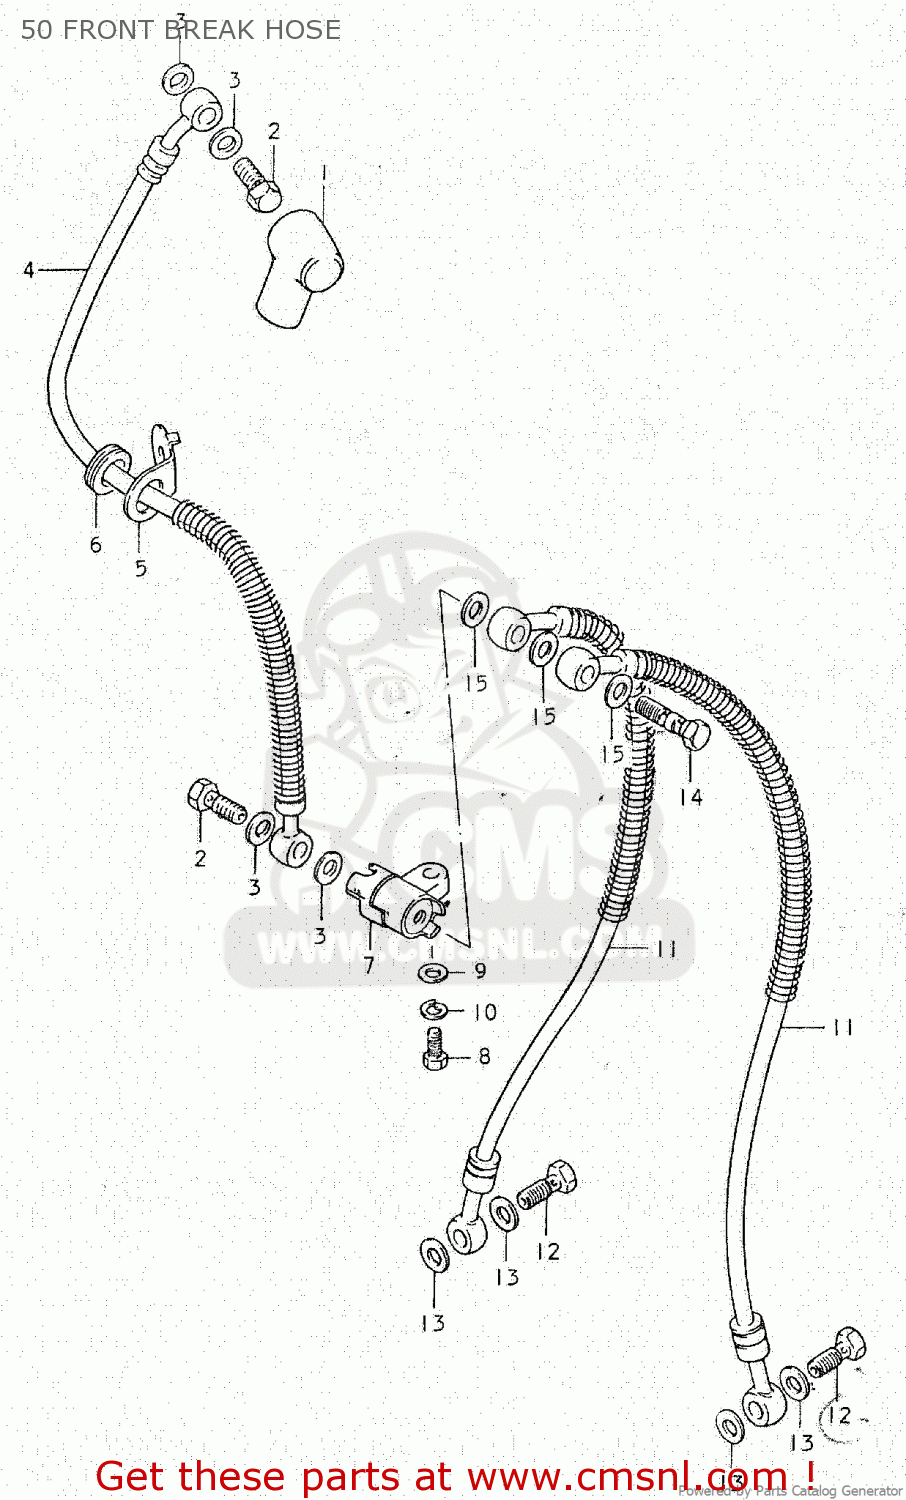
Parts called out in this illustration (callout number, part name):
1	BOOT,MASTER CYLINDER
2	BOLT UNION
3	WASHER
4	HOSE,BRAKE NO.1
5	GUIDE,BRAKE HOSE
6	GROMMET
7	JOINT,BRAKE HOSE
8	BOLT
9	WASHER
10	LOCK WASHER
11	HOSE,FRONT BRAKE
12	BOLT UNION
13	WASHER
